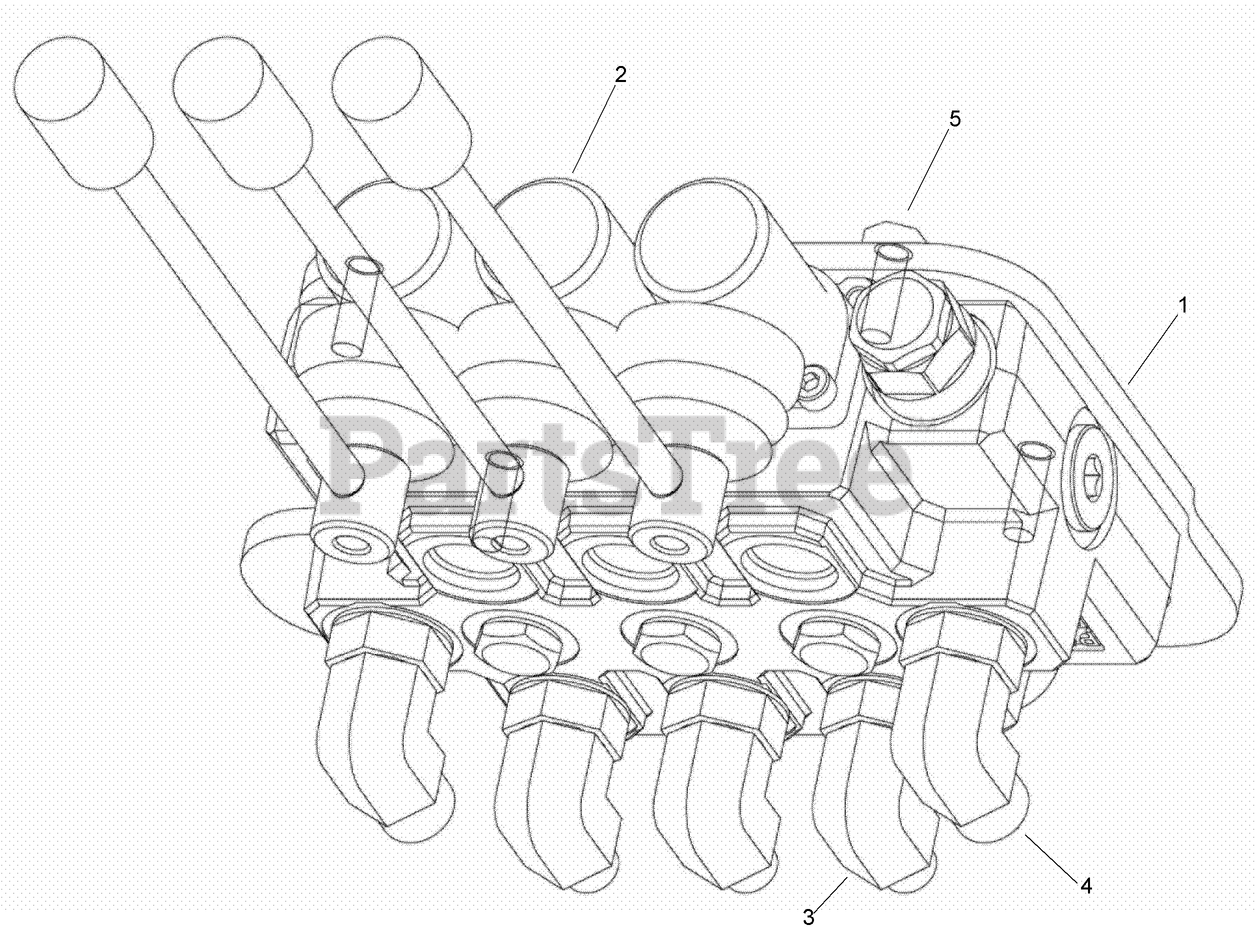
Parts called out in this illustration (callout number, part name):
1	PLATE-Valve Mount
2	VALVE-Auxiliary
3	ELBOW-90 Adj 37FL, 3/8 x 1/2 Tube
4	ELBOW-90 Adj 37FL, 1/2 Tube
5	SCREW, METRIC FLANGE FULL-M8 x 16
